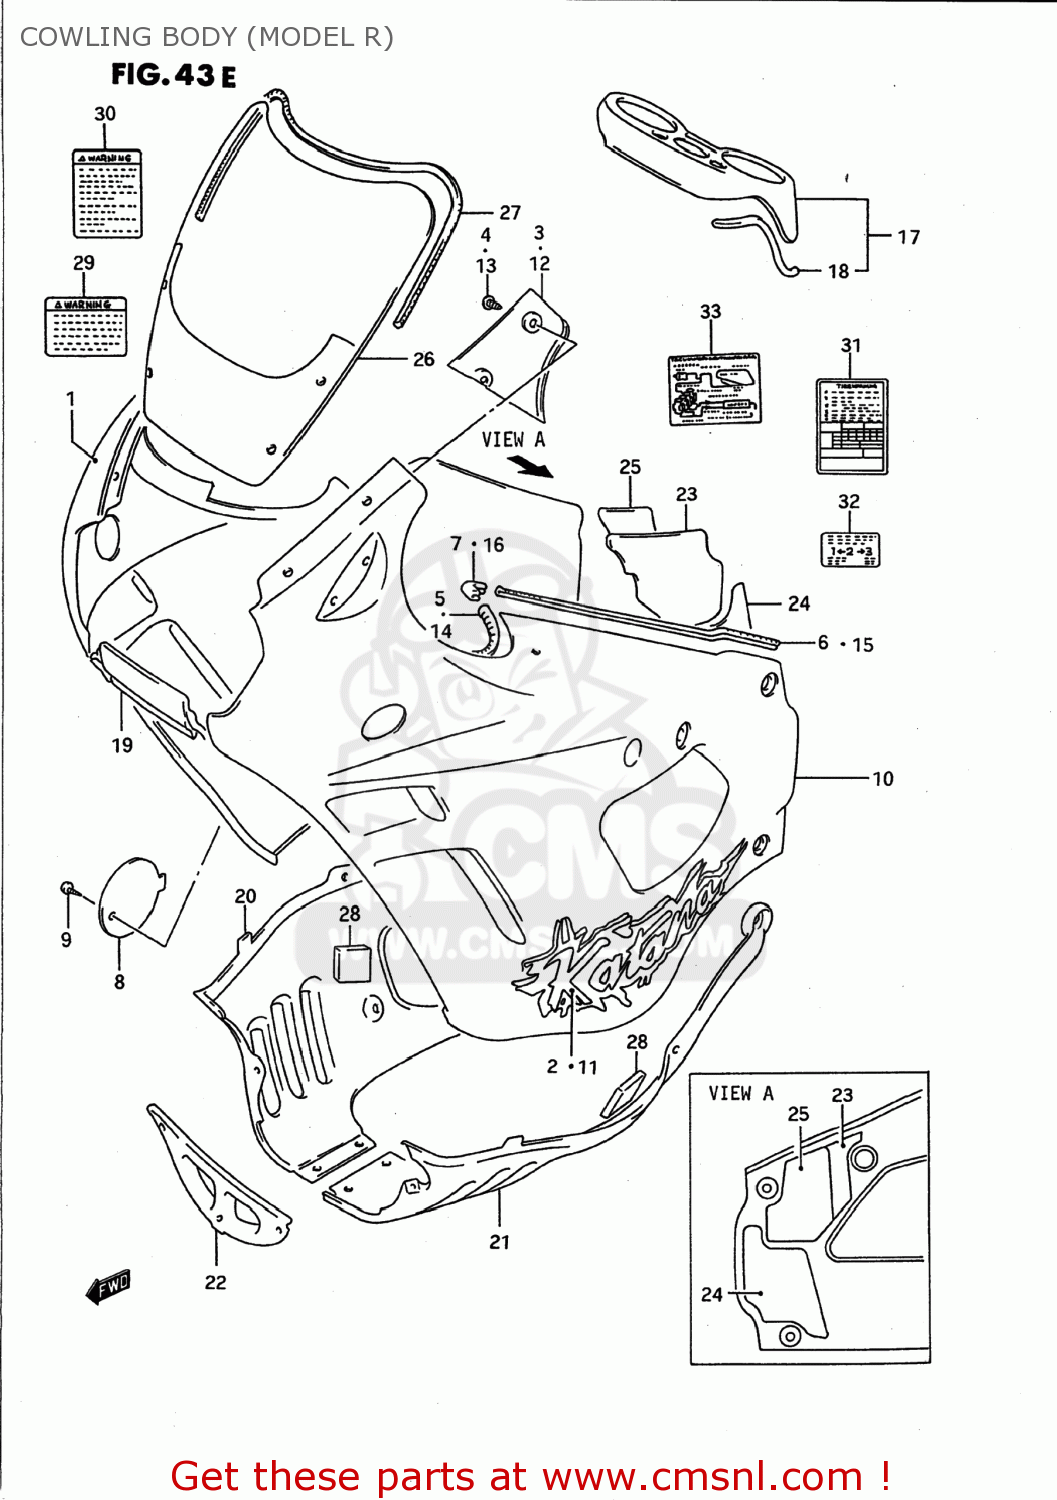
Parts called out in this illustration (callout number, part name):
1	COVER ASSEMBLY,COWLING,RIGHT
2	EMBLEM,BODY COWLING SIDE
3	COVER,COWLING METER SIDE,R
4	SCREW
5	MOLD,COWLING
6	MOLDING
7	JOINT,MOLDING END
8	LID,OIL
9	SCREW(6X16)
10	COVER ASSEMBLY,COWLING,LEFT
11	EMBLEM,BODY COWLING SIDE
12	COVER,COWLING METER SIDE,L
13	SCREW
14	MOLD,COWLING
15	MOLDING
16	JOINT,MOLDING END
17	COVER,METER
18	MOLDING,METER COVER
19	PANEL,COWLING CTR
20	COVER,COWLING UNDER,R
21	COVER,COWLING UNDER,L
22	COVER,COWLING UNDER FR
23	BALANCER SHEET,COWLING,R
24	SHEET,COWLING BALANCER
25	CUSHION,COWLING,R
26	WINDSCREEN
27	MOLDING,WINDSCREEN
28	CUSHION,UNDER COWLING
29	LABEL
30	LABEL (WARNING SCREEN)
31	LABEL (TIRE AIR PRESSURE)
32	LABEL (REAR SHOCK ABSORBER)
33	LABEL (VACUUM HOSE ROUTING)
